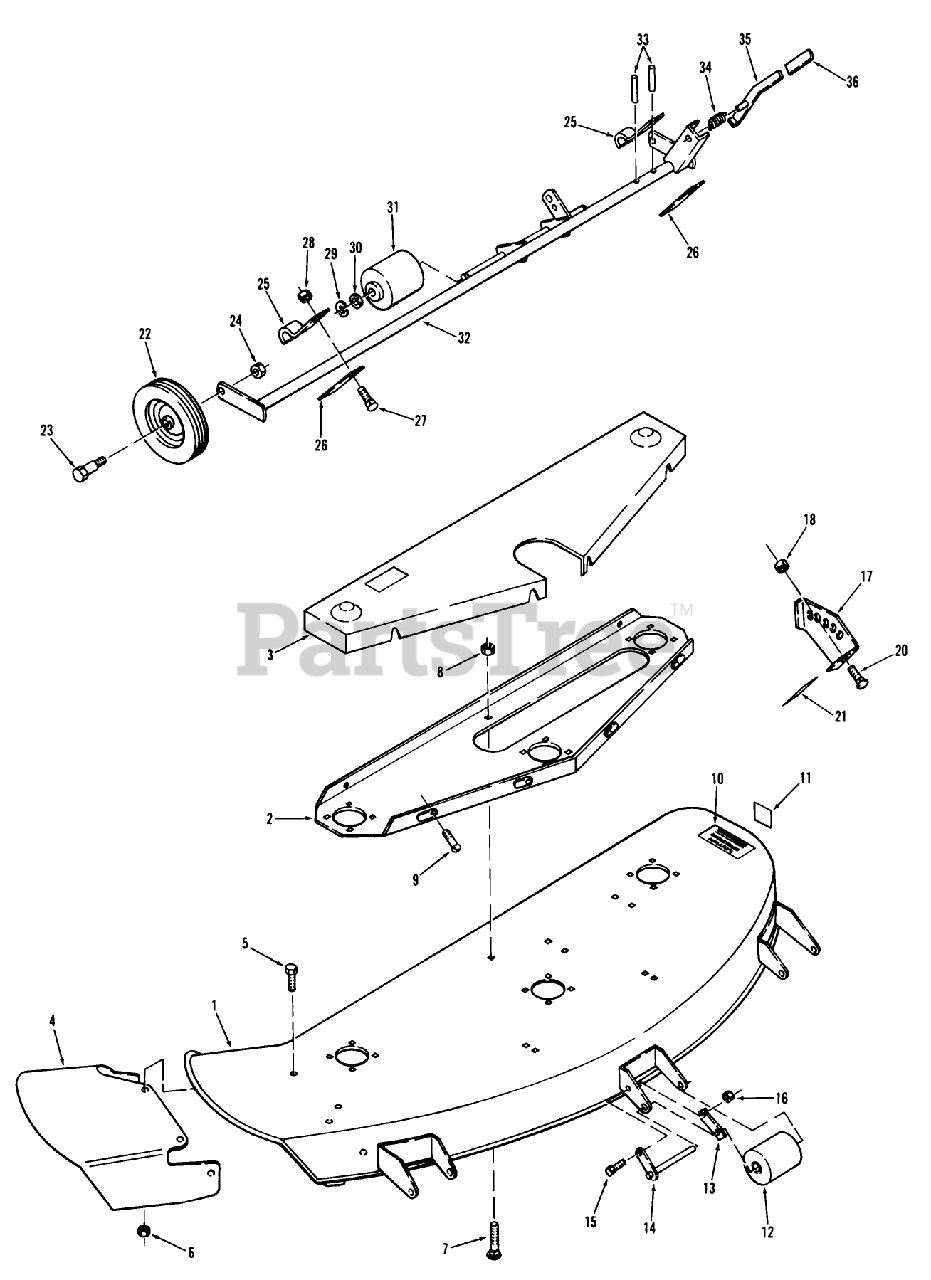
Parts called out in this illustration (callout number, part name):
1	Deck
1	Deck-42"
2	Support
3	Cover
3	Belt Cover
4	Chute Extension
5	Bolt
6	Nut
7	Bolt-Carriage
8	NUT
9	Bolt
10	Screw
10	Decal
11	DECAL-WHEEL HORSE
12	Roller
13	SPRING ROLLER STOP
14	Roller Shaft
15	H H C S
16	Nut
17	LH QUADRANT R
17	Quadrant
18	NUT
20	Bolt
21	Decal Height Adjustment
22	Wheel
23	BOLT-SHOULDER
24	Nut
25	Machine Bolt
26	Bar
27	Bolt
28	NUT
29	E Ring
30	Washer
30	WASHER
31	Roller
32	Gage Wheel Support
32	Support Ass-y. Gage Wheel
33	PIN-SPIROL
34	SPRING-COMPRESSION
35	Lever
35	LEVER ASSY R
